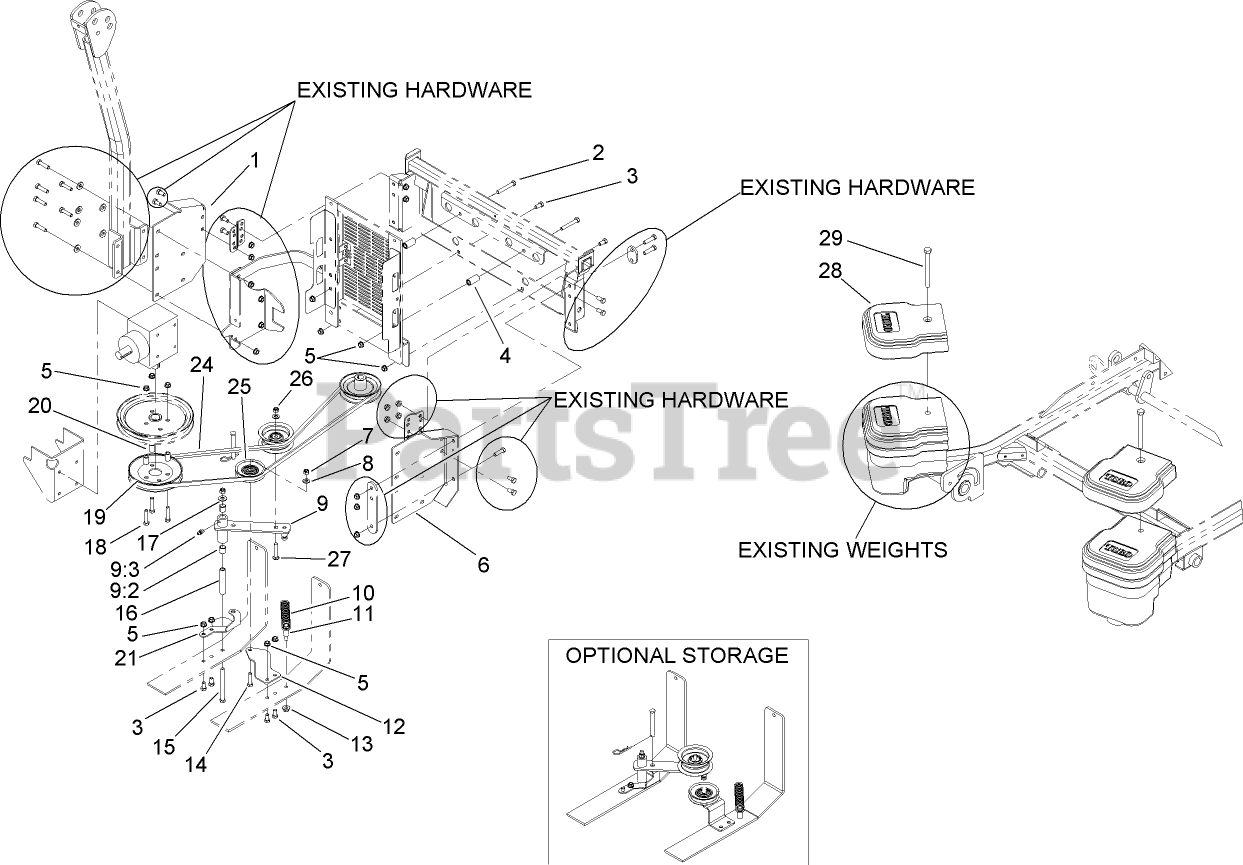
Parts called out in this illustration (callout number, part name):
1	BRACKET-MOUNT, BAGGER, RH
2	SCREW-HH
3	SCREW-HH
4	SPACER
5	NUT-HHF, WHIZ
6	BRACKET-MOUNT, BAGGER, LH
7	NUT-LOCK, NI
8	WASHER-FLAT
9	IDLER ARM ASM
9:2	SLEEVE-BEARING
9:3	FITTING-GREASE
10	SPRING-EXTENTION
11	ANCHOR-SPRING
12	BRACKET-MOUNT, PULLEY
13	NUT-HF
14	SCREW-HH
15	SCREW-HH
16	BUSHING-TIGHTENER, PIVOT
17	WASHER-FLAT
18	SCREW-HH
19	PULLEY-A
20	SPACER
21	BRACKET-LOCK, IDLER ARM
24	BELT-V
25	SHEAVE
26	PULLEY-IDLER, FLAT
27	SCREW-CARR
28	Weight
29	SCREW-HH
